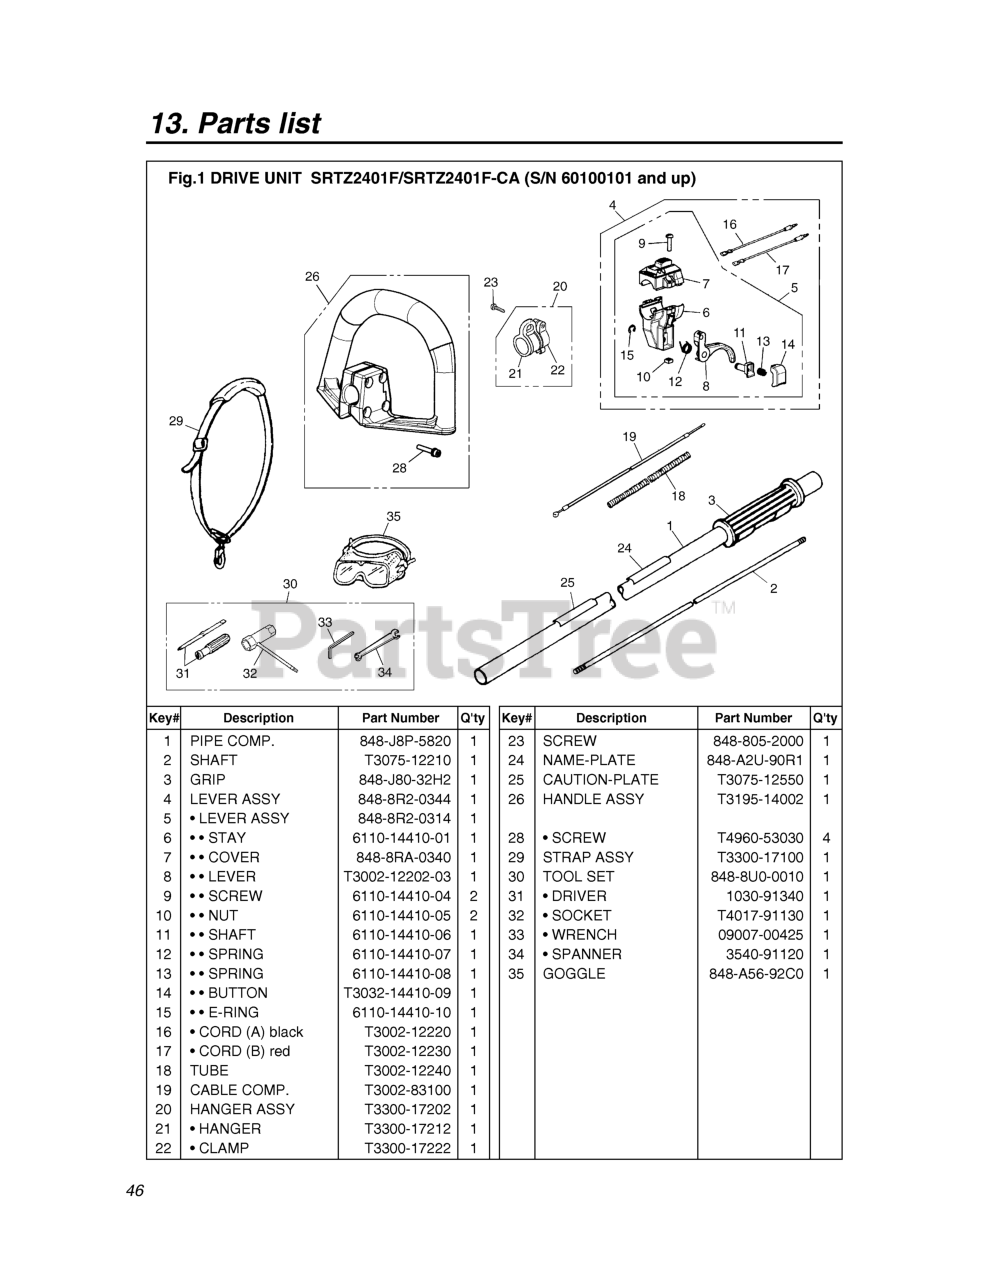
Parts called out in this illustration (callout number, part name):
1	PIPE COMP
2	SHAFT
3	GRIP
4	LEVER ASSY
5	LEVER
7	COVER
8	LEVER
16	CORD (A), BLACK
17	CORD (B), RED
18	TUBE
19	CABLE COMP
20	HANGER ASSY
23	SCREW
24	NAMEPLATE
25	CAUTION-PLATE
26	HANDLE ASSY
28	SCREW
29	STRAP ASSY.
30	TOOL-SET
31	DRIVER
34	SPANNER
35	GOGGLE
